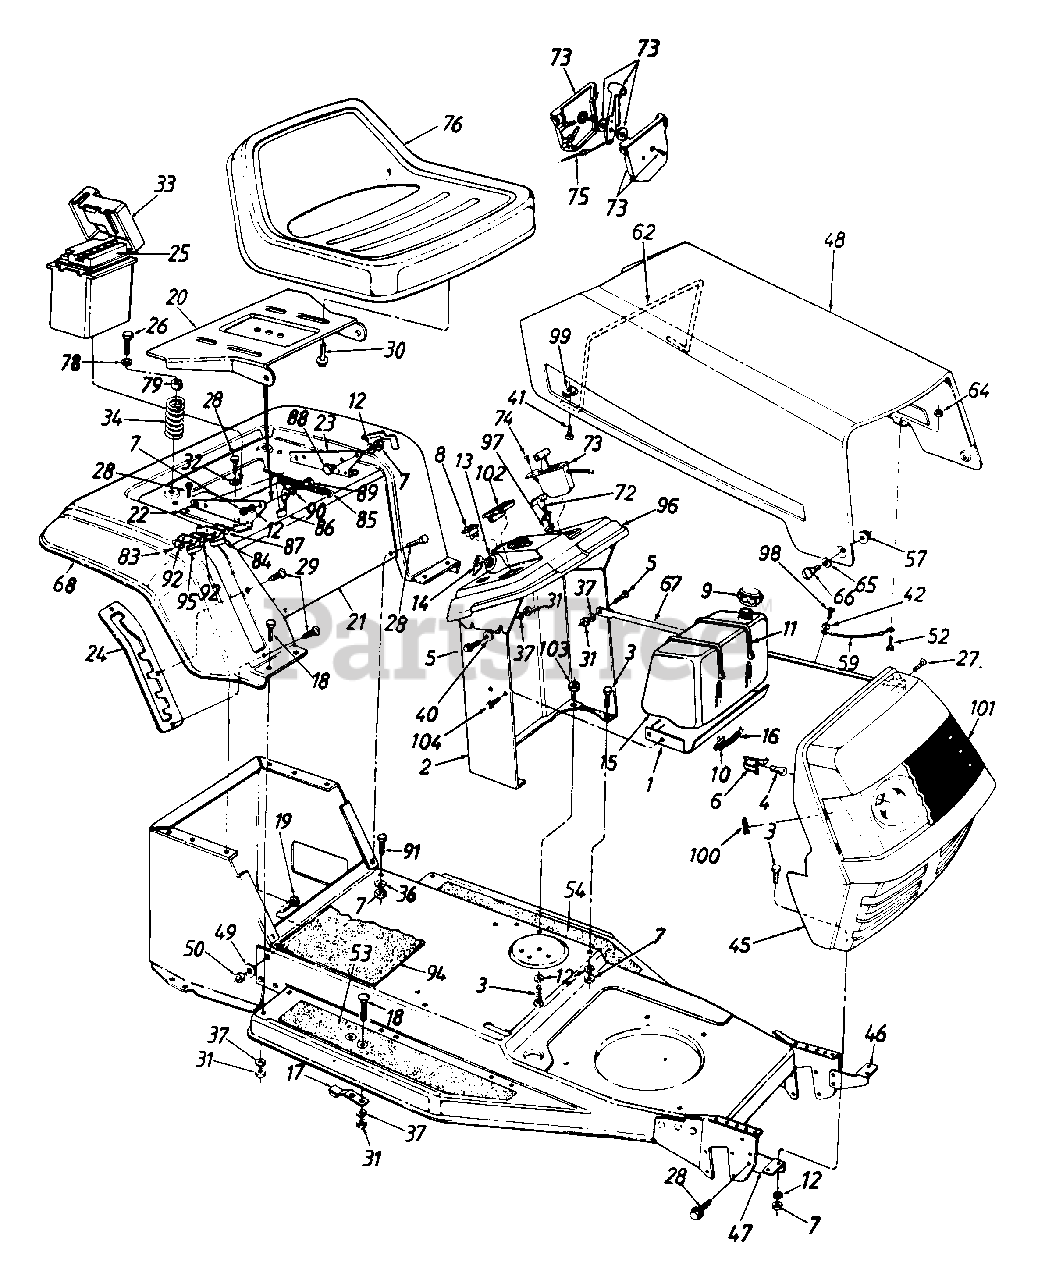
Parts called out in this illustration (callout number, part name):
3	Hex Bolt 5/16-18 x .75" Lg.
4	Bulb
5	Hex Bolt 1/4 x .62" Lg.
6	Socket
7	Hex Nut 5/16-18 Thd.
8	Light Switch
9	Gas Cap
10	Hose Clamp
11	Cable Tie
12	L-Wash. 5/16" I.D.
13	Ignition Switch
14	Ignition Key
15	Fuel Tank
16	Gas Line 15" Long
17	Blade Brake Ass'y.
18	Carriage Bolt 1/4-20 x .62"
19	Ribbed Neck Bolt 3/8-24 x .8"
20	Seat Pivot Brkt.
25	Battery
26	Hex Self-Tap Screw 5/6-18 x 1.25" Lg.
27	Truss Mach. Scr. 1/4-20 x .75" Lg.
28	Hex AB-Tap Scr. 5/16 x .75" Lg.
29	Torx Mach. AB-Tap Scr. 1/4 x
30	Hex Self-Tap Scr. 3/8-16 x .75" Lg.
31	Hex Nut 1/4-20 Thd.
32	External L-Wash. 5/16" I.D.
33	Battery Box w/Cover
34	Compression Spring
36	Bell-Wash. 5/16" I.D.
37	L-Wash. 1/4" I.D.
40	Bell-Wash..265" I.D. x .75"
41	Pan Hd. Scr. 10-24 x .75" Lg.
42	Fl-Wash..218" I.D. x .62"
47	Grille Mtg. Brkt.- R.H.
50	Hex L-Nut 3/8-24 Thd.
52	Truss Mach. Scr. #10-24 x .5" Lg.
53	Foot Pad - R.H.
54	Foot Pad - L.H. .62" Lg.
57	Lock Nut 1/4-28 Thd.
59	Hood Stop
62	Hood Spring
64	Hex Sems Nut #10-24 Thd.
65	Spr. Wash..39" I.D. x .62" O.D.
66	Shld. Bolt
72	Choke Control
73	Throttle Control Box
74	Truss AB-Tap Scr. #10 x .5"
75	Throttle Wire (B&S)
76	Seat Assembly (Low Back)
78	Fl-Wash..344" I.D. x .88" O.D.
79	Bushing
83	Hex Tap Scr. #8 x .5" Lg.
84	Safety Switch (Seat)
85	Ext. Spring 5.31" Lg.
86	Seat Lift Brkt.
87	Insulator Boss Plate
88	Shld. Bolt .437" Dia. x .162" Lg.
89	Shld. Bolt .437" Dia. x .268" Lg.
90	Spr. Wash..445" I.D. x .75" O.D.
91	Hex Wash. Hd. Scr. 5/16-18 x .62" Lg.
92	Insulator Plate
94	Center Foot Pad
95	Safety Switch (Seat)
96	Dash Panel
97	Retainer Clip
98	Truss Mach. B-Tap Scr. #10 x .5" Lg.
99	Speed Nut
100	Internal Cotter Pin 5/16" Dia.
101	Lens
102	Ammeter
103	Hex Jam Nut 5/16-18 Thd.
104	Hex Wash. Hd. Tap Scr. 1/4-20 x .5" Lg.
